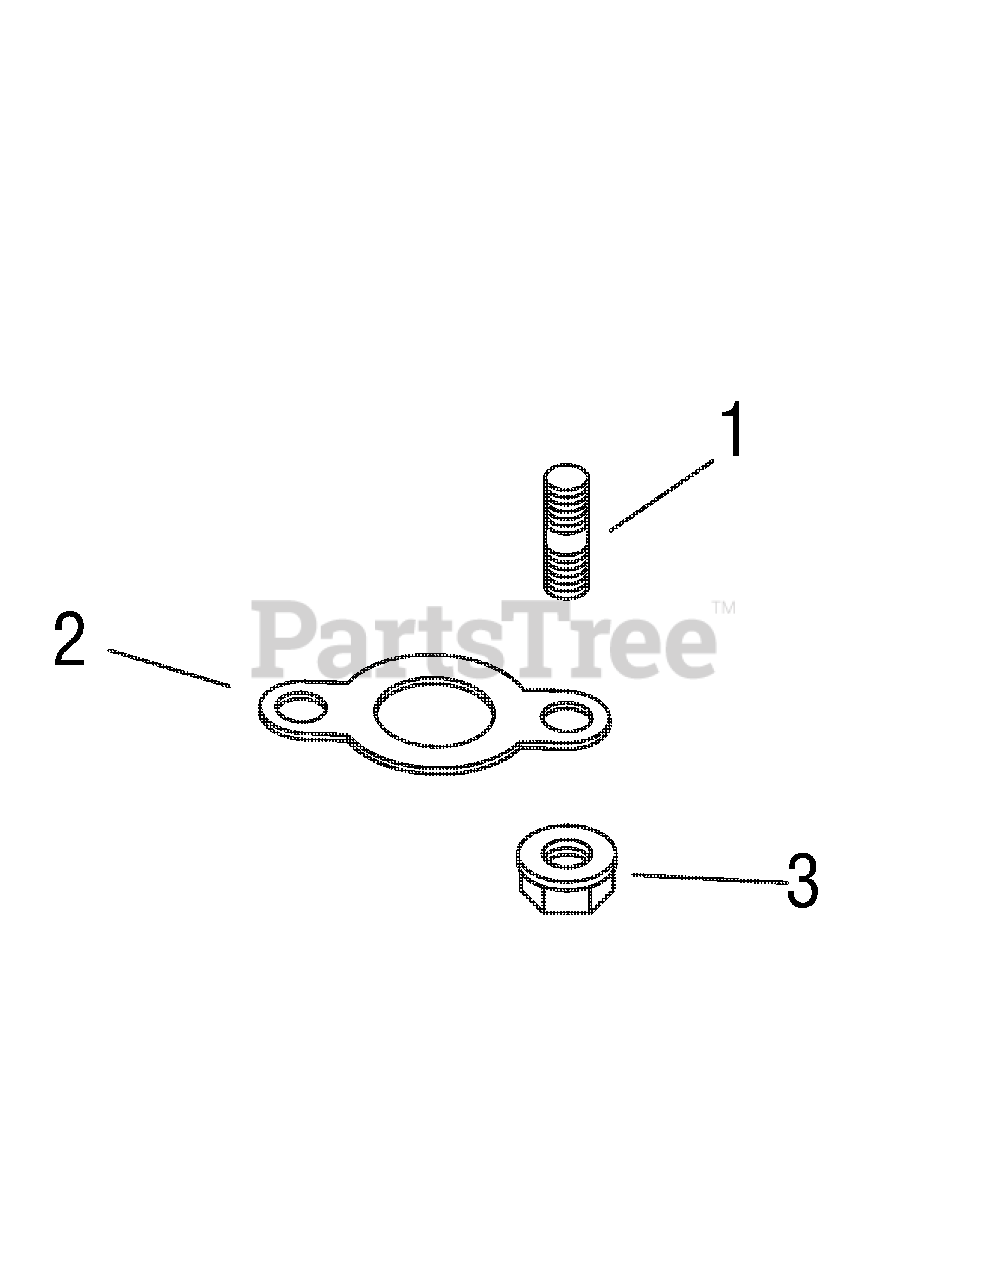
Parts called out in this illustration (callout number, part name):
1	Stud, M8 x 1.25 x 33
2	Gasket, exhaust manifold
3	Nut, hex. flange M8 x 1.25
